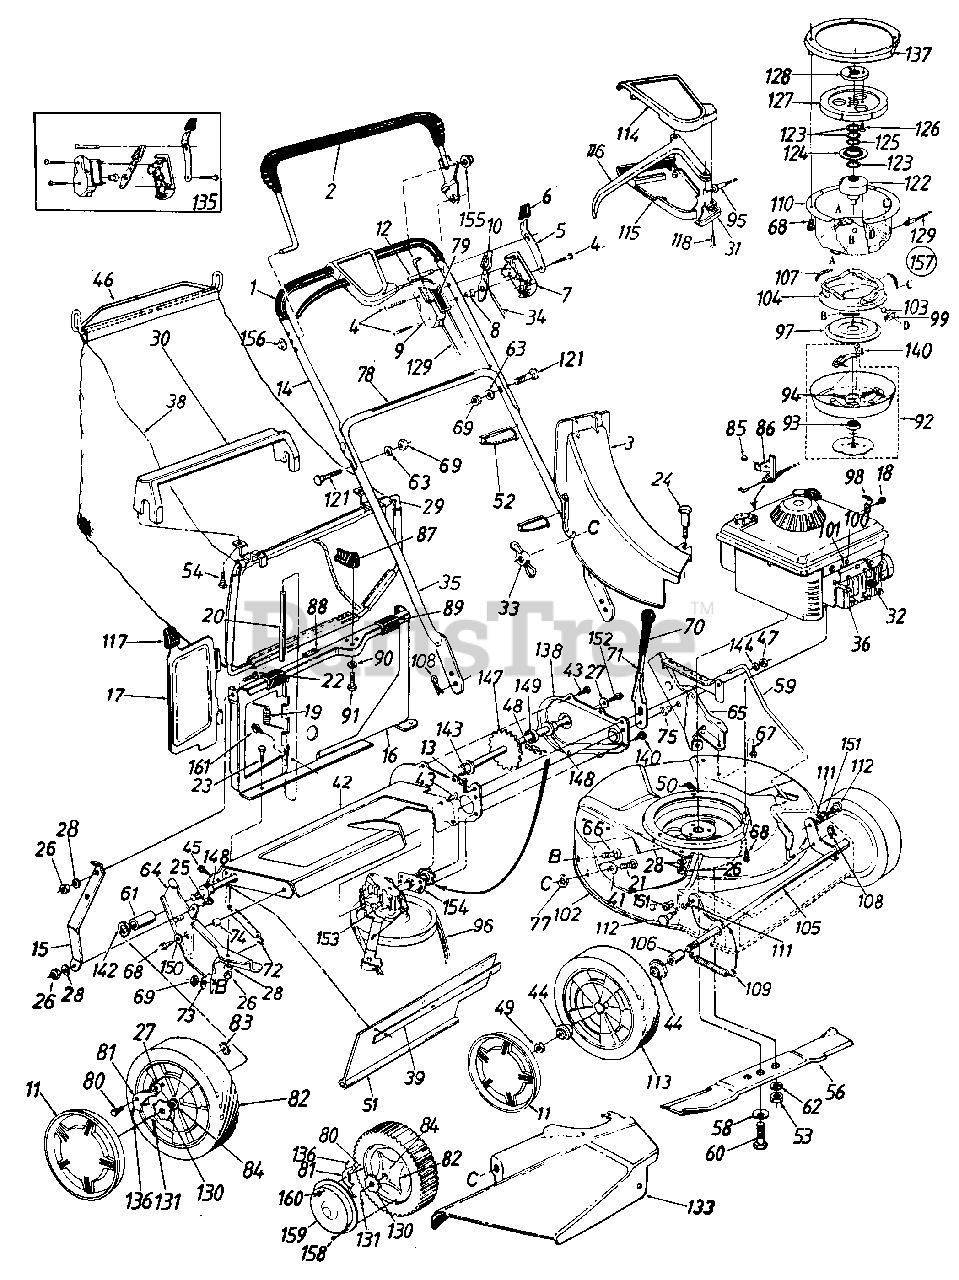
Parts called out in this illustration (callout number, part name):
1	GRIP-SHRINK-25 IN
2	HANDLE ASSY-CONTROL
3	CHUTE ASSY-TOP DISCH
4	SCREW-TRUSS MACH
5	SPRING-LOCKOUT
6	KNOB
7	PANEL HALF-CONTROL
8	PIN-CONTROL DISC
9	PANEL HALF-CLUTCH
10	LEVER-THROTTLE CONT-REV
11	HUB CAP
12	PIN-LOCKING
13	PIN-COTTER-3/32 DIA X .75
14	HANDLE-UPPER-CHROME
15	BRACKET-PANEL SUP
16	PANEL ASSY-CATCHER
17	DOOR-TOP DISCHARGE
18	SCREW-HEX B-TAP #10 X .38
19	SPRING-TORSION
21	BOLT-CARRIAGE 1/4-20 X .62
22	SCREW-TRUSS MACH 1/4-20 X .50
23	SCREW-HEX 1/4-20 X .50
24	SCREW-SHLD
25	SCREW-HEX 1/4-20 C .62
26	NUT-HEX 1/4-20
27	WASHER-SPRING BELL
28	LOCK WASHER 1/4 DIA
29	FRAME-GRASSCATCHER
30	HANDLE-BAG-BLACK
31	CAP-CABLE MTG
32	INSULATOR-SPARK PLUG
33	NUT-WING
34	WIRE-THROTTLE 58 LG
35	HANDLE-LOWER PAINTED
38	BAG-GRASS-CONV
39	STRIP-RETAINING
41	WASHER-FL-.344 ID X .62 OD X .033
42	AXLE ASSY-CHAIN
43	SCREW-HEX B-TAP 1/4 X .38
44	BEARING-BALL
45	SCREW-HEX WASH HD
46	HANDLE-GRASSCATCHER
47	NUT-HEX LOCK 3/8-24
48	#48 CHAIN 1/2 PITCH
49	NUT-HEX INS L-1/2-20
51	FLAP-RR
52	TIE-CABLE
53	NUT-HEX 3/8-24
54	SCREW-TAP .215 X 1
56	BLADE-21IN
58	WASHER-BELL
59	ROD-HGT ADJ 1.50 X 19.42
60	SCREW-HEX 7/16 N.F. X 2 GR.5
61	SPACER-.513 ID X .703 OD X .69
62	WASHER-LOCK-3/8
63	WASHER-LOCK-5/16
64	BRACKET ASSY-HDLE-RH
65	BRACKET ASSY-HDLE-LH
66	BOLT-CARRIAGE 5/16-18 X .62
67	SCREW-HEX WASH HD 5/16-18X1/2
68	SCREW-HEX HD TAP
69	NUT-HEX 5/16-18
71	LEVER-HGT ADJ
72	SPRING-EXTENSION
73	WASHER-BELL .337 X .867 X .057
75	SPACER-SHLD .500 X .100
77	RETAINER-BOLT 1/4X.50 OD
78	LABEL-BBC-INST
80	SCREW-SHLD .342 DIA X .268
81	PAWL
82	WHEEL ASSY W/TIRE
83	NUT-FLAT WELD 1/4 X 20
86	BRACKET-CABLE
87	KNOB-LOCKING
88	STRIP-FOAM 1/4X1.0
89	CLIP-PANEL BAG
90	WASHER-SHAKE PROOF
91	SCREW-HEX WASH 1/4-20X.75
92	HOUSING-CLUTCH BLADE
93	BEARING-BALL
95	CABLE-CLUTCH X 50.0
96	BELT-V 3/8 X 31.0
97	CONE-CLUTCH
98	CLAMP-CASING
99	BALL-BLOCK
100	SCREW-HEX WASH HD TAP
101	CLIP-CASING
104	CONE-BRAKE CUP
105	AXLE ASSY-FR-290
107	SPRING-EXTENSION
108	PIN-INTERN COT-5/16 DIA
109	SPRING-EXTENSION
110	HOUSING-CLUTCH
111	WASHER-INTERN L 3/8 X.56 OD X .018
112	SCREW-SHLD
113	WHEEL ASSY W/TIRE 7X1.75BB
114	COVER-HALF-CONTROL
115	COVER-HALF CONT-LWR
116	LEVER-CONTROL
117	KNOB
118	SCREW-FL C-SUNK AB
121	BOLT-CARRIAGE-CURV 5/16-18 X 1.38
122	ADAPTER-FIXED PULLEY
123	WASHER-SERRATED
124	PULLEY-MOVABLE
125	WASHER-WAVE
126	SCREW-FL HD TORXB 1/4X20 X .62
128	ADAPTER-FLYWHEEL
129	CABLE-CLUTCH 49 IN
130	RATCHET
131	PIN-COTTER-1/8 DIA X 1.00
133	DEFLECTOR-CHUTE
135	KIT-THROTTLE CONTROL
136	SPRING-NYLON
137	PLATE-ENGINE MTG
138	COVER-CHAIN
140	SCREW-HEX WASH SF TAPP
142	WASHER-FL
143	BEARING-HEX FLANGE
144	WASHER-FL-.385 ID X .87 OD X .06
147	SHAFT ASSY-REAR
148	BEARING-HEX FLANGE .506 ID
149	WASHER-FL-.531 X .930 OD X .050
150	WASHER-FL-.531 ID X 1.25 OD X 1.00
151	BEARING-NYLINER
152	SCREW-1/4-20 X .62
153	TRANSMISSION-COMP
154	BEARING-CUP HEX
156	NUT-SPEED
157	CLUTCH ASSY-BLADE
161	SCREW-HEX B-TAP #10 X .38
